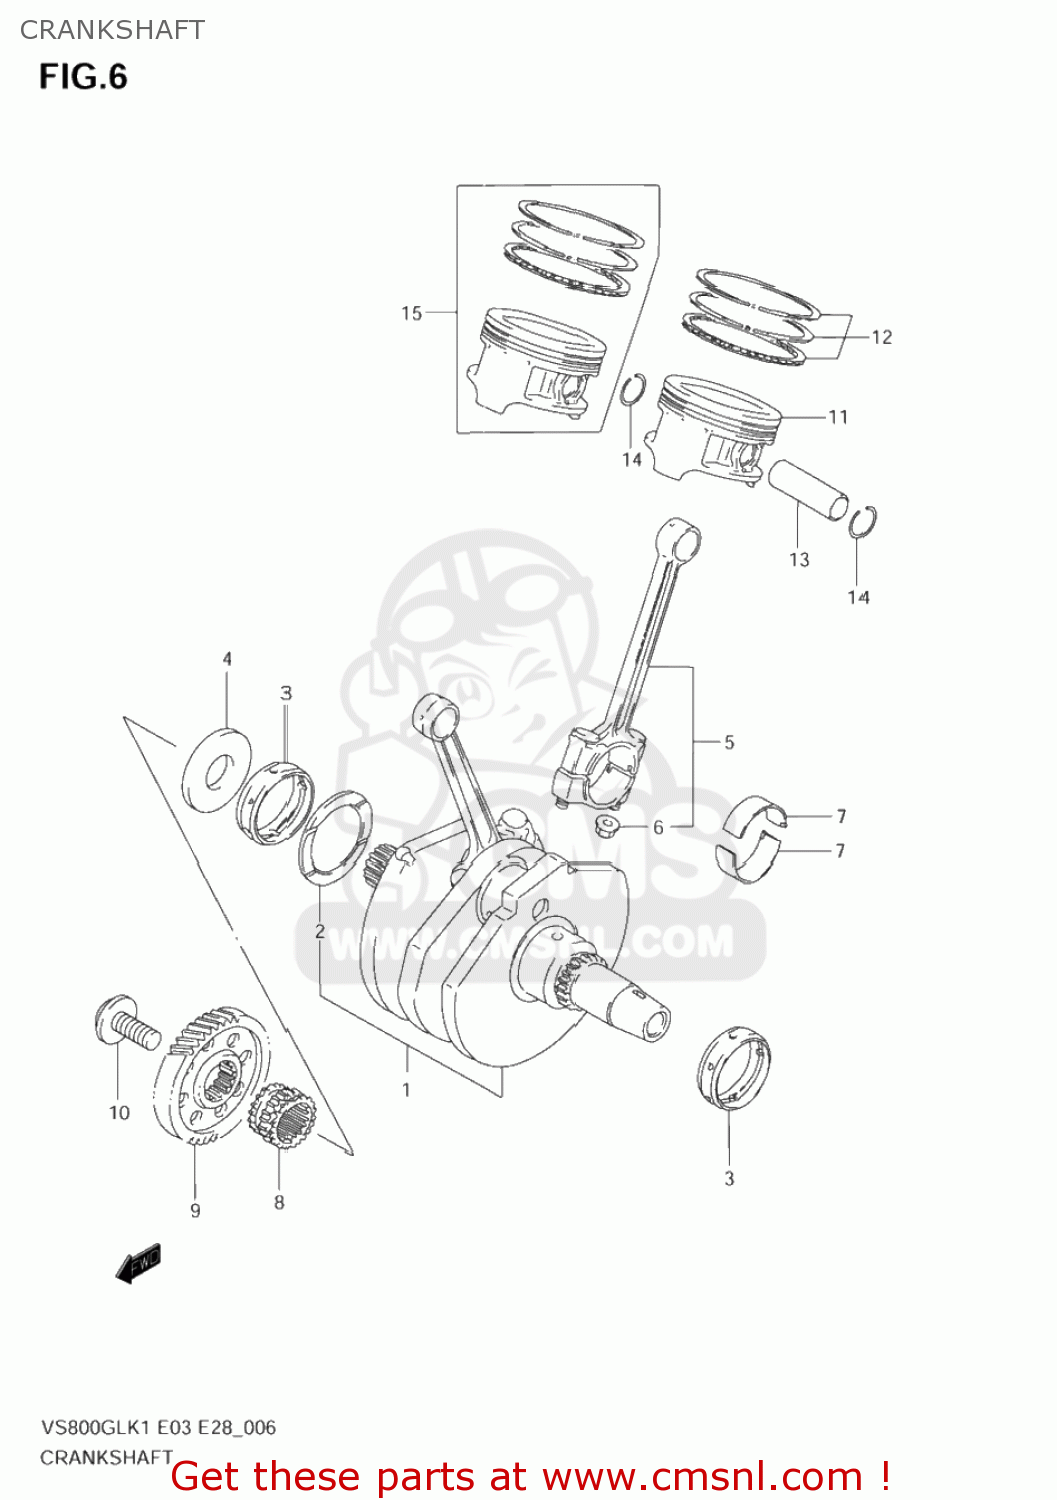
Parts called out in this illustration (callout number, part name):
1	CRANKSHAFT SET
2	WASHER(48.1X64X1.94)
3	METAL,CRANKSHAFT
4	WASHER,CRANK THRUST
5	CONNECTING ROD ASSY
6	NUT
7	BEARING,CRANK PIN
8	SPROCKET,CAM CHAIN DRIVE,R
9	GEAR,PRIMARY DRIVE
10	BOLT(12X28)
11	PISTON
12	RING SET,PISTON
13	PIN,PISTON
14	CIRCLIP,PISTON PIN
15	PISTON SET(OS:0.5)
